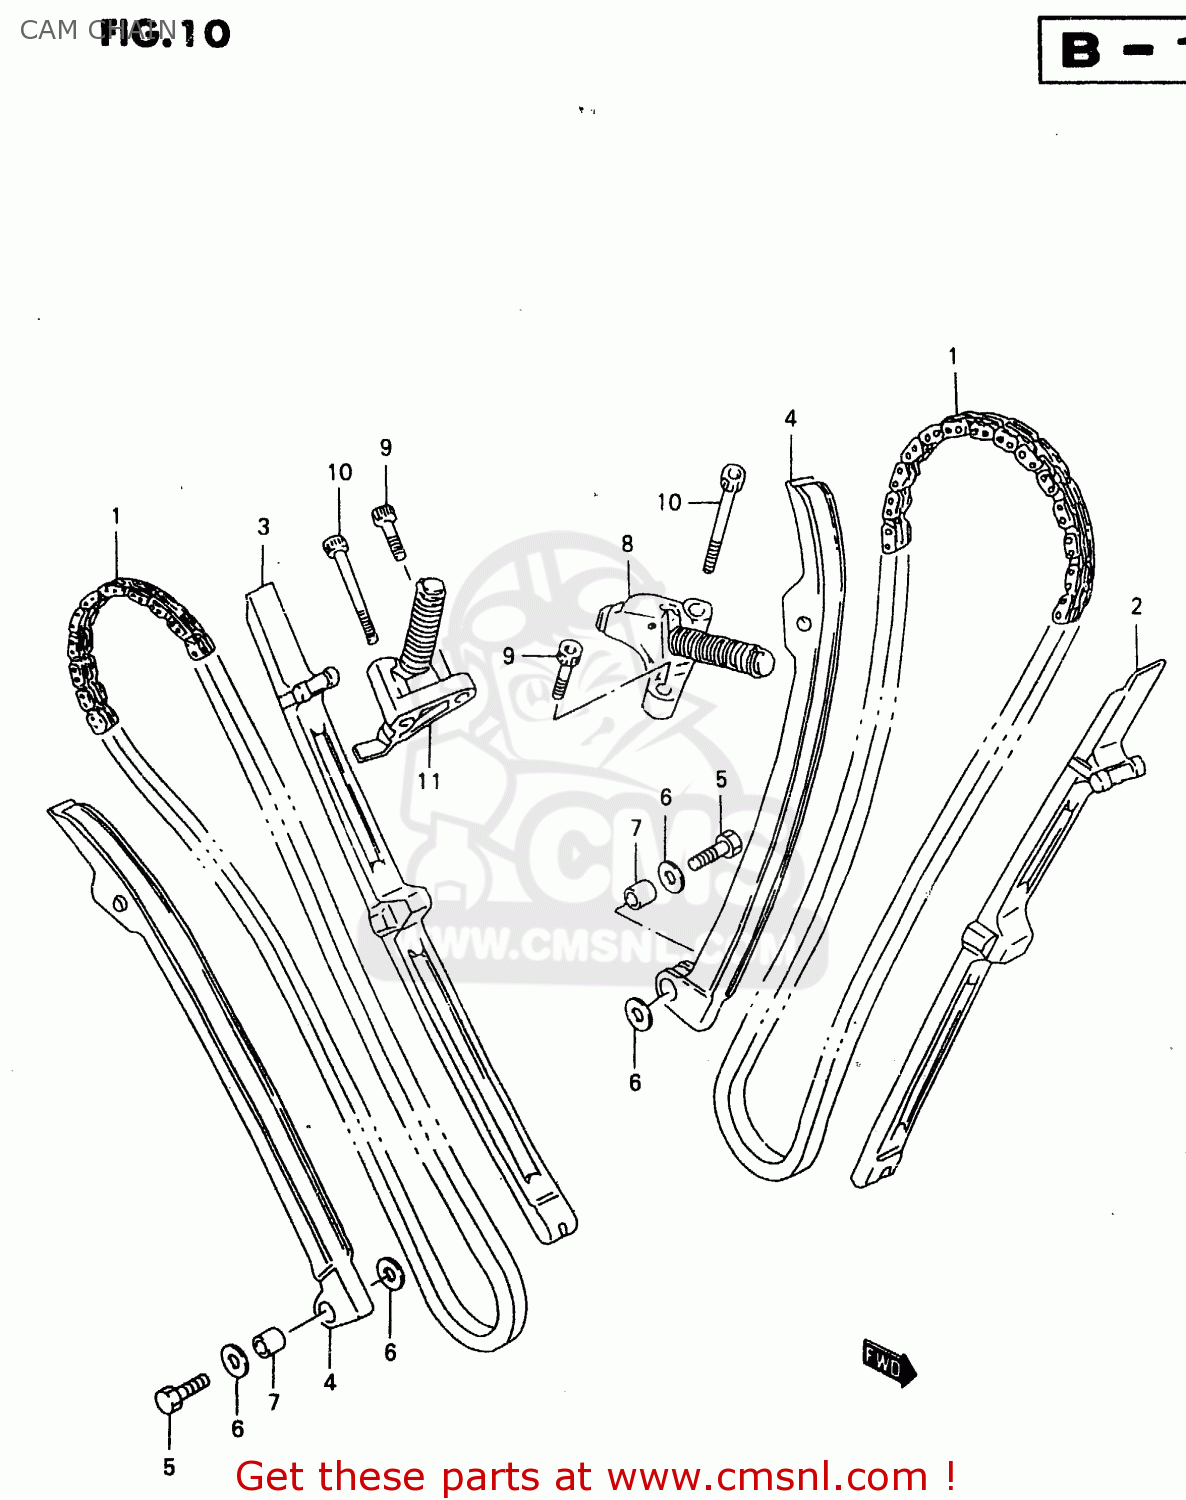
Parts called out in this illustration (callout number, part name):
1	CHAIN,CAMSHAFT DRIVE
2	GUIDE,CAM CHAIN
3	GUIDE,CAM CHAIN RR
4	TENSIONER,CAM CHAIN
5	BOLT(6X26)
6	WASHER
7	SPACER(6X11X9)
8	ADJUSTER ASSEMBLY,FRONT TENSIONER
9	BOLT,CRKCASE,R
10	BOLT
11	ADJUSTER ASSEMBLY,REAR TENSIONER
